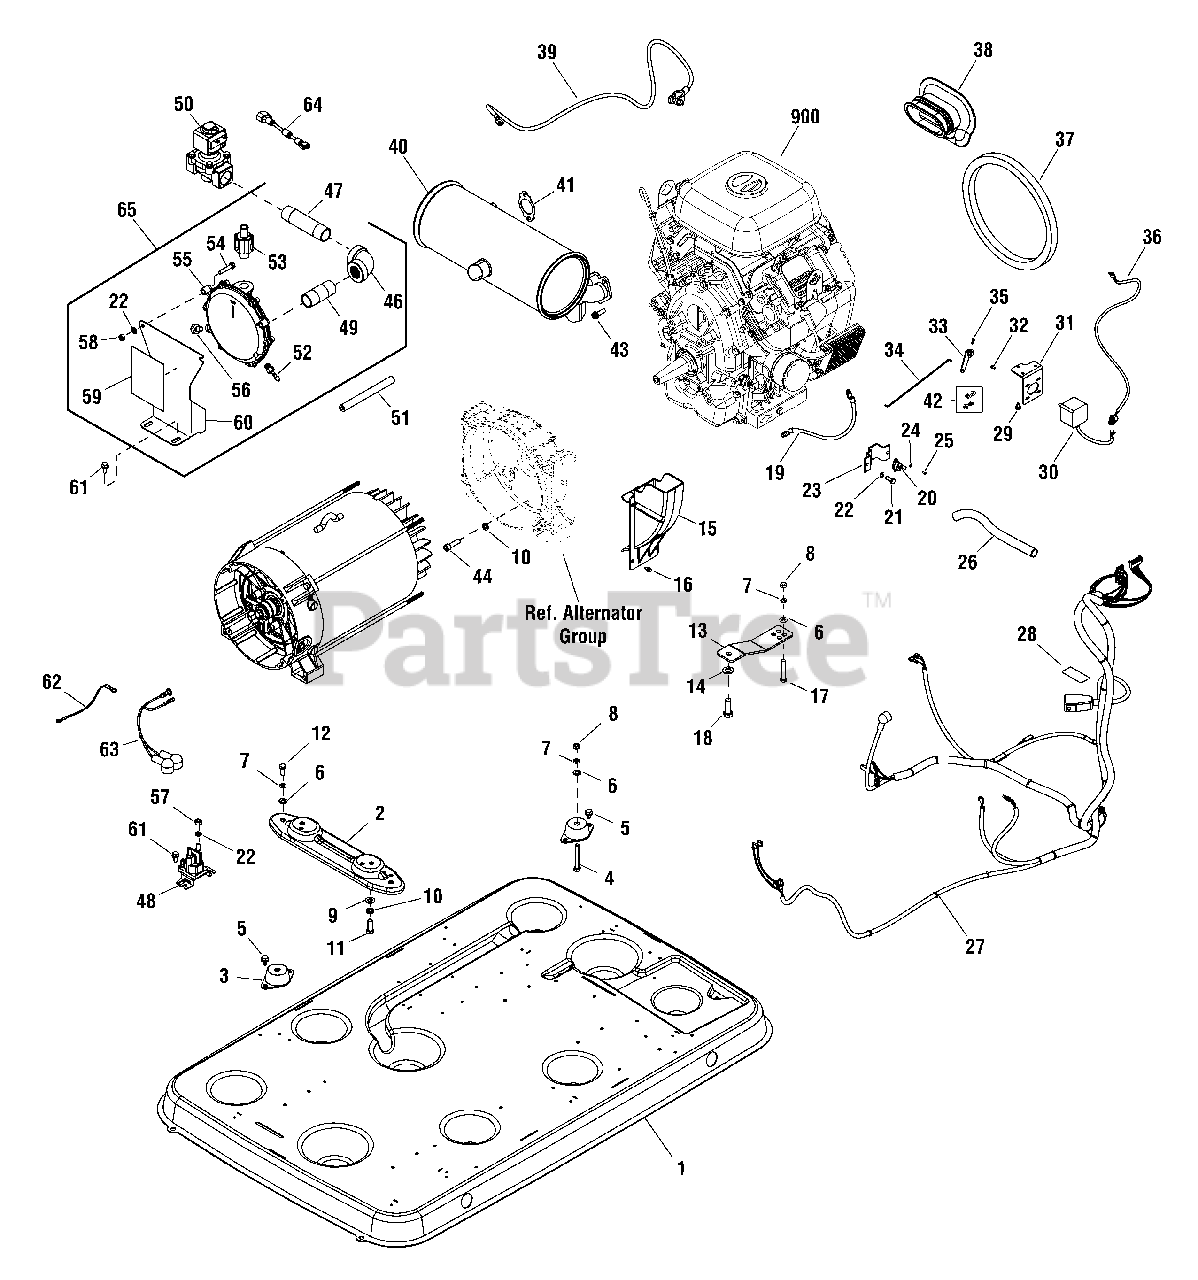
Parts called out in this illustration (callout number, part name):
1	BASE
3	MOUNT, Vibration
4	* CAPSCREW, Hex Head, 5/16-18 x 2-1/2
6	* WASHER, Flat, M8
7	* WASHER, Lock, M8
8	* NUT, 5/16-18
9	* WASHER, Flat, M10
10	* WASHER, Lock, 3/8
11	* CAPSCREW, Hex Head, 3/8-16 x 1
12	* CAPSCREW, Hex Head, 5/16-18 x 3/4
14	* WASHER, Flat, M12
16	* SCREW, M5-0.8 x 10
17	* CAPSCREW, Hex Head, 5/16-18 x 2
18	CAPSCREW, Hex HEad, M12-1.75 x 35
21	CAPSCREW, Hex Head, M6-1.0 x 16
22	* WASHER, Lock, 1/4
24	* WASHER, Shakeproof, #4
25	SCREW
27	HARNESS, Wiring
28	DECAL SHEET, Warnings
30	STEPPER MOTOR
31	BRACKET
32	* CAPSCREW, Hex Head, M3-0.5 x 6
33	ARM, Link
35	* CAPSCREW, Hex Head, M3-0.5 x 8
36	HARNESS, Wiring
39	WIRE, Battery, Ground
43	* SCREW, M8 x 25
48	SOLENOID, Starter
50	SOLENOID
53	VALVE, LP/NG Switch
54	* CAPSCREW, Hex Head, M6-1.0 x 30
55	REGULATOR
57	* NUT, 1/4-20
58	* NUT, Hex, M6-1
59	DECAL SHEET, Warnings
60	BRACKET
61	BOLT
62	WIRE, Ground Relay
65	FUEL REGULATOR ASSEMBLY
900	** ENGINE
